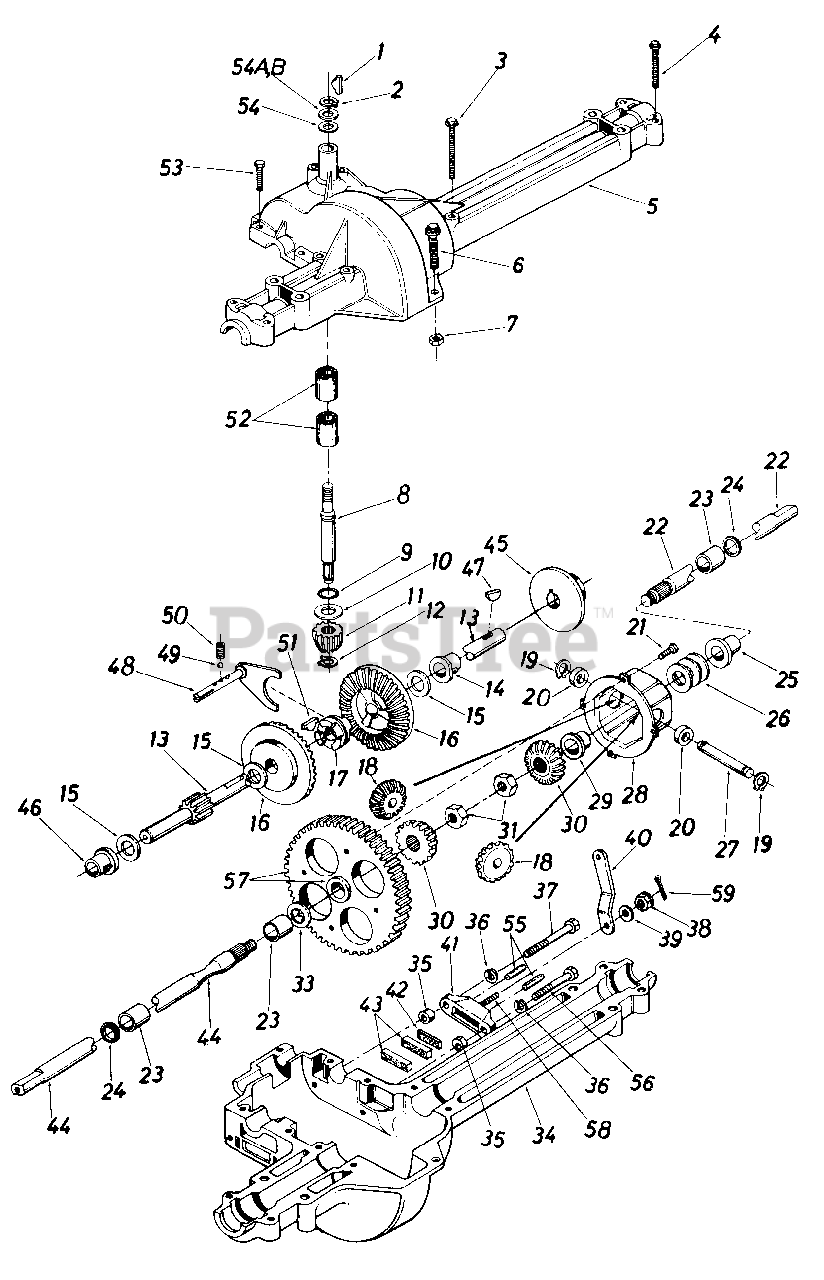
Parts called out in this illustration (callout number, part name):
1	#4 Hi-Pro Key 3/32 x 5/8" Dia.
2	Snap Ring .625" Shaft
3	Hex Bolt 1/4-20 x 1.75" Lg.*
4	Hex Bolt 1/4-20 x 1.25" Lg.*
5	Upper Housing
6	Hex Fl-Bolt 1/4-20 x .75" Lg.
7	Hex Nut 1/4-20 Thd.*
8	Input Shaft
9	Square Seal 5/8" I.D.
10	Thrust Washer 5/8" I.D. x 1.25" O.D.
11	Pinion Input 14T
12	Retaining Ring 7/16" Ext.
13	Drive Shaft-R.H.
14	Flange Brg. 5/8" I.D. x 3/4" Lg.*
15	Fl-Wash.
16	Bevel Gear 42T
17	Clutch Collar
18	Miter Gear 15T
19	Snap Ring
20	Thrust Bearing 1/2" I.D. x 1.0" O.D.
21	Pan Head Scr. 1/4-20 x .50" Lg. w/Patch
22	Axle R.H.
23	Sleeve Bearing 3/4" I.D. x 1.0" Lg.
24	Oil Seal 3/4" I.D.
25	Flange Bearing 3/4" I.D. x 15/16" Lg.
26	Fl-Wash. .760" I.D. x 1.49" O.D.
27	Cross Shaft
28	Differential Housing Ass'y.
30	Miter Gear
31	Hex Ins. L-Nut 1/2-20 Thd.
33	Fl-Wash. .75" I.D. x 1.5" O.D.
34	Lower Housing
35	Spacer 53" O.D. x 3/8" Lg.
36	L-Wash. 1/4" I.D.
37	Hex Bolt 1/4-20 x 1.50" Lg. (Grade 5)
38	Castle Nut 5/16-24 Thd.
39	Fl-Wash. .34" I.D. x .875" O.D.
40	Actuating Arm-R.H.
41	Brake Yoke
42	Puck Plate
43	Brake Puck
44	Axle L.H.
45	Brake Disc
46	Flange Bearing 5/8" I.D. x 15/16" Lg.
47	Woodruff Key 3/16 x 5/8 HT
48	Shift Fork Ass'y.
49	Ball Detent .250" Dia.
50	Spring Detent
51	#9 Hi-Pro Key 3/16" x 3/4" Dia. HT
52	Needle Brg. 5/8" I.D. x 1/2" Lg.
53	Hex Bolt 1/4-20 x 1.00" Lg
54	Fl-Wash. 5/8" I.D. x .030
54A	Fl-Wash. 5/8" I.D. x .040
54B	Fl-Wash. 5/8" I.D. x .020
55	Actuating Pin 5/16" Dia.
56	Hex Bolt 1/4-20 x 1.50" Lg. (Grade 5)
57	Differential Gear 72T Ass'y. w/Bearing
58	Sq. Hd. Bolt 5/16-24 Thd.
59	Cotter Pin 3/32" Dia. x .50" Lg.
